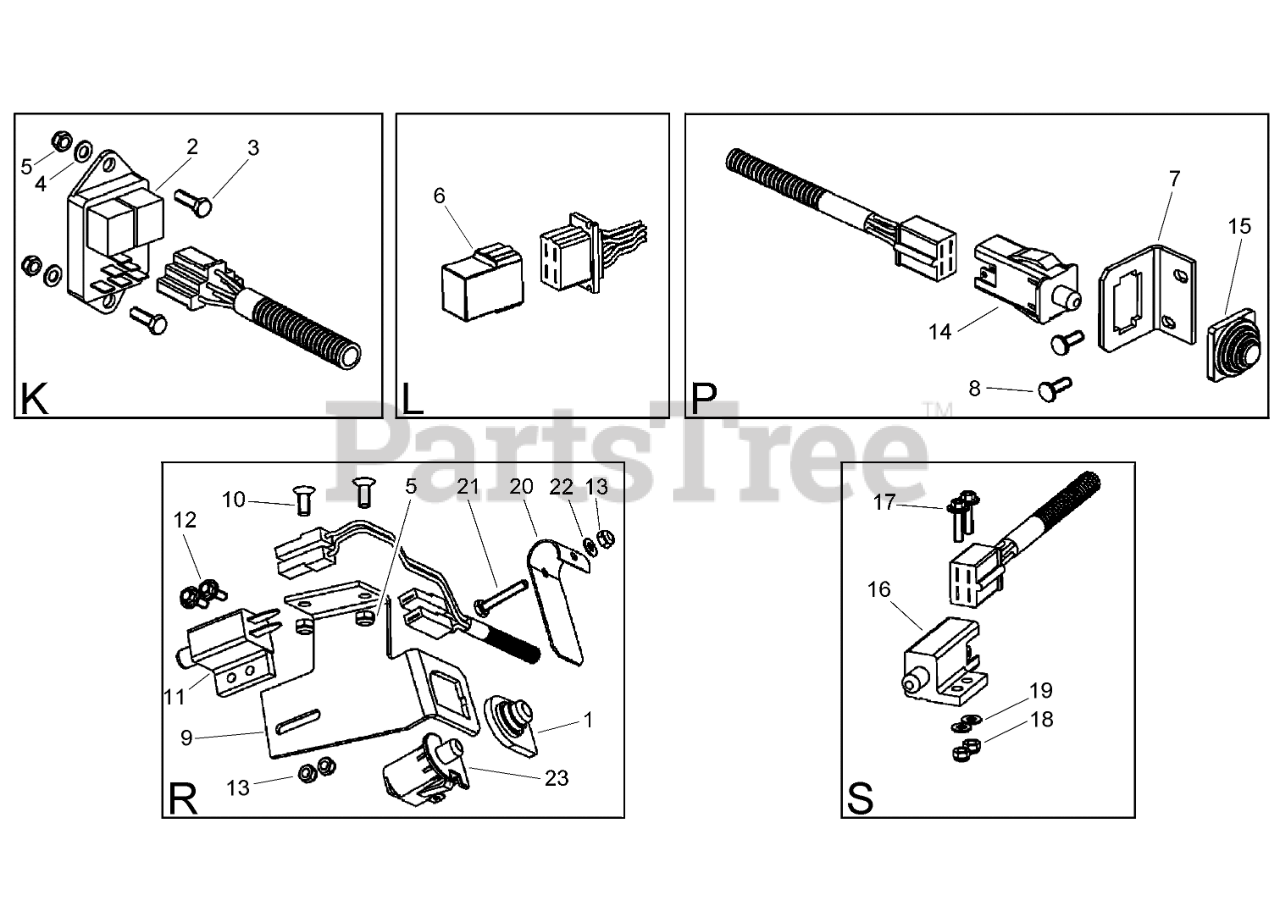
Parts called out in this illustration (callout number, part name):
1	COVER-PROTECTIVE
2	MODULE-CLUTCH
3	SCREW-HH
4	WASHER
5	NUT-LOCK
6	CIRCUIT-MEMORY
7	Holder-Switch
9	Holder-Switch
11	SWITCH-POLE, SINGLE
13	NUT-HEX
14	Switch-Delta
15	Cover-Switch
16	Switch-Delta
18	NUT-LOCK
19	WASHER
20	Lever-Spring
21	SCREW-HEX
22	Washer
23	SWITCH-DELTA
